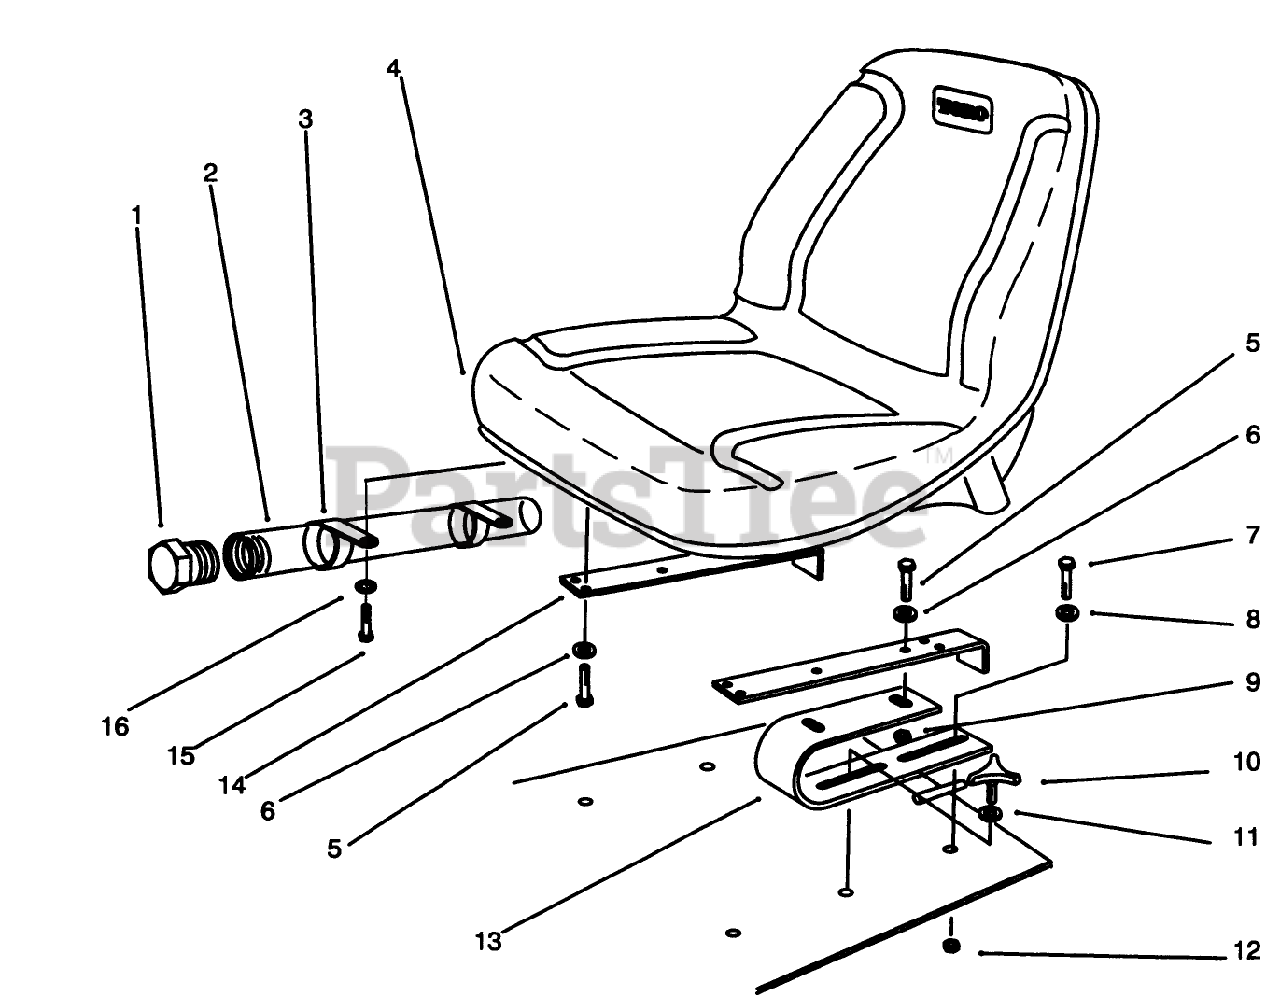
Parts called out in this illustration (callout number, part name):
1	Cap-Tube
2	TUBE-MANUAL
3	TIE ROD
4	Seat
5	SCREW-HH
6	WASHER-LOCK
7	BOLT-SHOULDER
8	WASHER-FLAT
9	NUT-HEX
10	KNOB-SEAT
11	WASHER
12	NUT-LOCK, NI
13	Spring-Seat
14	Mount-Seat
